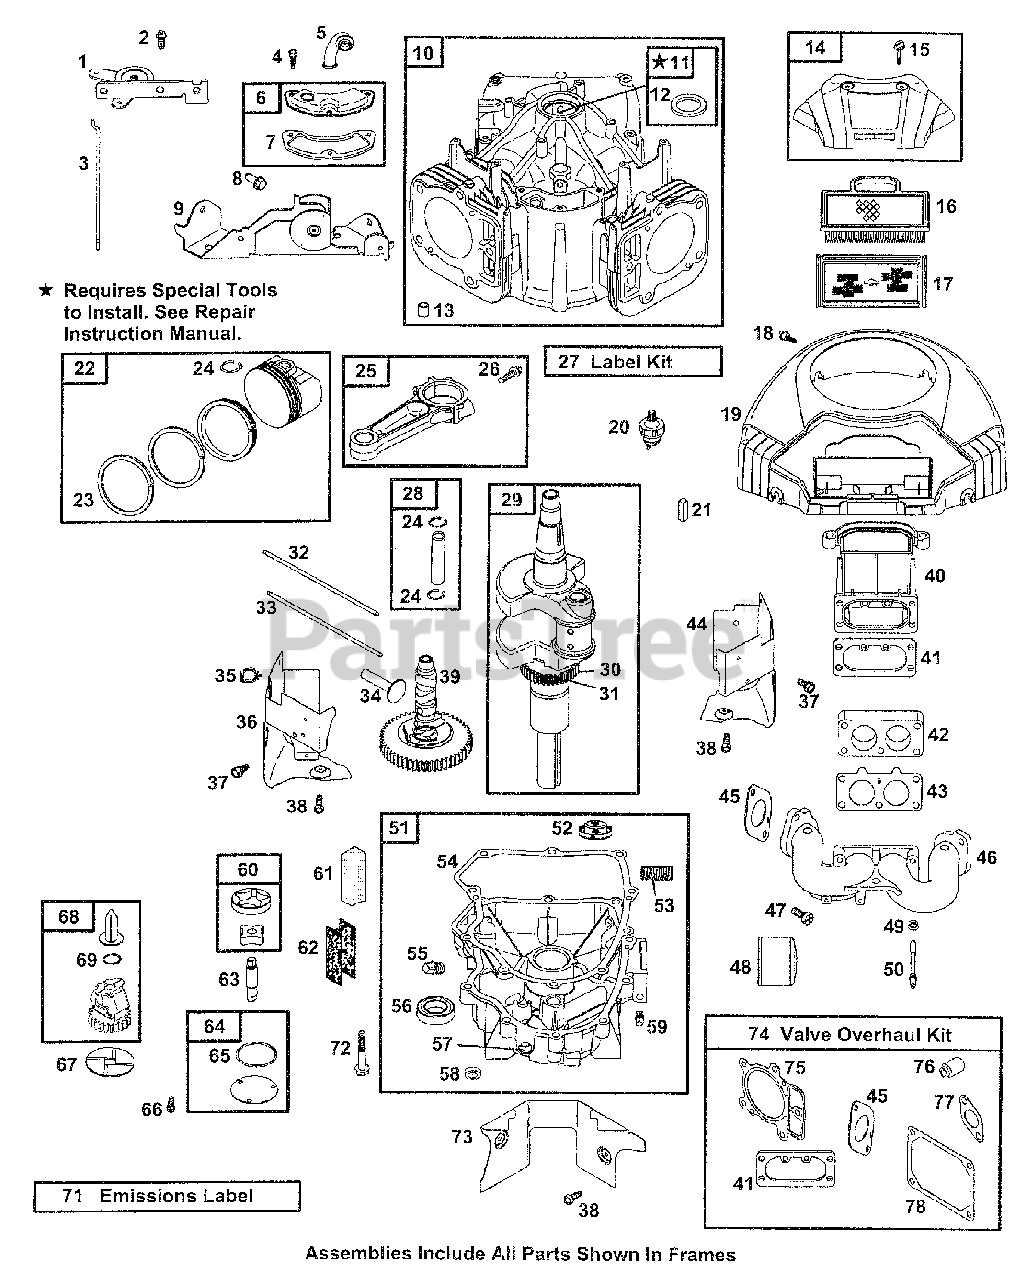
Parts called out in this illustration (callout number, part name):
1	Choke Control Bracket
2	Screw (Choke Control Bracket)
3	Choke Link
4	Screw (Breather Assembly)
5	Breather Tube
6	Breather Assembly
7	Breather Gasket
8	Screw (Control Bracket)
9	Control Bracket
10	Cylinder Assembly
11	Bushing/Seal Kit (Magneto Side)
12	Oil Seal (Magneto Side)
13	Locating Pin
14	Air Cleaner Cover
15	Air Cleaner Knob
16	Air Cleaner Cartridge Filter
17	Pre-Cleaner Filter
18	Screw (Blower Housing)
19	Blower Housing
20	Oil Pressure Switch
21	Flywheel Key
22	Piston Assembly
23	Ring Set
24	Piston Pin Lock
25	Connecting Rod
26	Screw (Connecting Rod)
28	Piston Pin
29	Crankshaft
30	Timing Key
31	Timing Gear
32	Rod-Push (Steel)
33	Rod-Push (Aluminum)
34	Valve Tappet
36	Air Guide Cover (Cylinder #1)
37	Screw (Air Guide Cover)
38	Screw (Air Guide Cover)
40	Air Adapter
41	Air Cleaner Gasket
42	Carburetor Spacer
43	Intake Gasket
44	Air Guide Cover (Cylinder #2)
45	Intake Gasket
46	Intake Manifold
47	Screw (Intake Manifold)
48	Oil Filter
49	Nut (Carburetor)
50	Stud (Carburetor)
51	Engine Sump
52	Oil Pump Screen
53	Oil Filter Nipple
54	Crankcase Gasket
55	Oil Drain Plug
56	Oil Seal (PTO Side)
57	Governor Crank Bushing
58	Governor Shaft Seal
59	Oil Plug
60	Oil Pump
61	Oil Collector
62	Breather Retainer
63	Pump Shaft
64	Oil Pump Cover
65	O-Ring Seal (Oil Pump Cover)
66	Screw (Oil Pump Cover)
67	Washer (Governor Gear)
68	Governor Gear
69	Governor Shaft Retainer
71	Emissions Label
72	Screw (Engine Sump)
73	Air Guide Cover
74	Valve Overhaul Kit
75	Cylinder Head Gasket
76	Valve Seal
77	Exhaust Gasket
78	Rocker Cover Gasket
